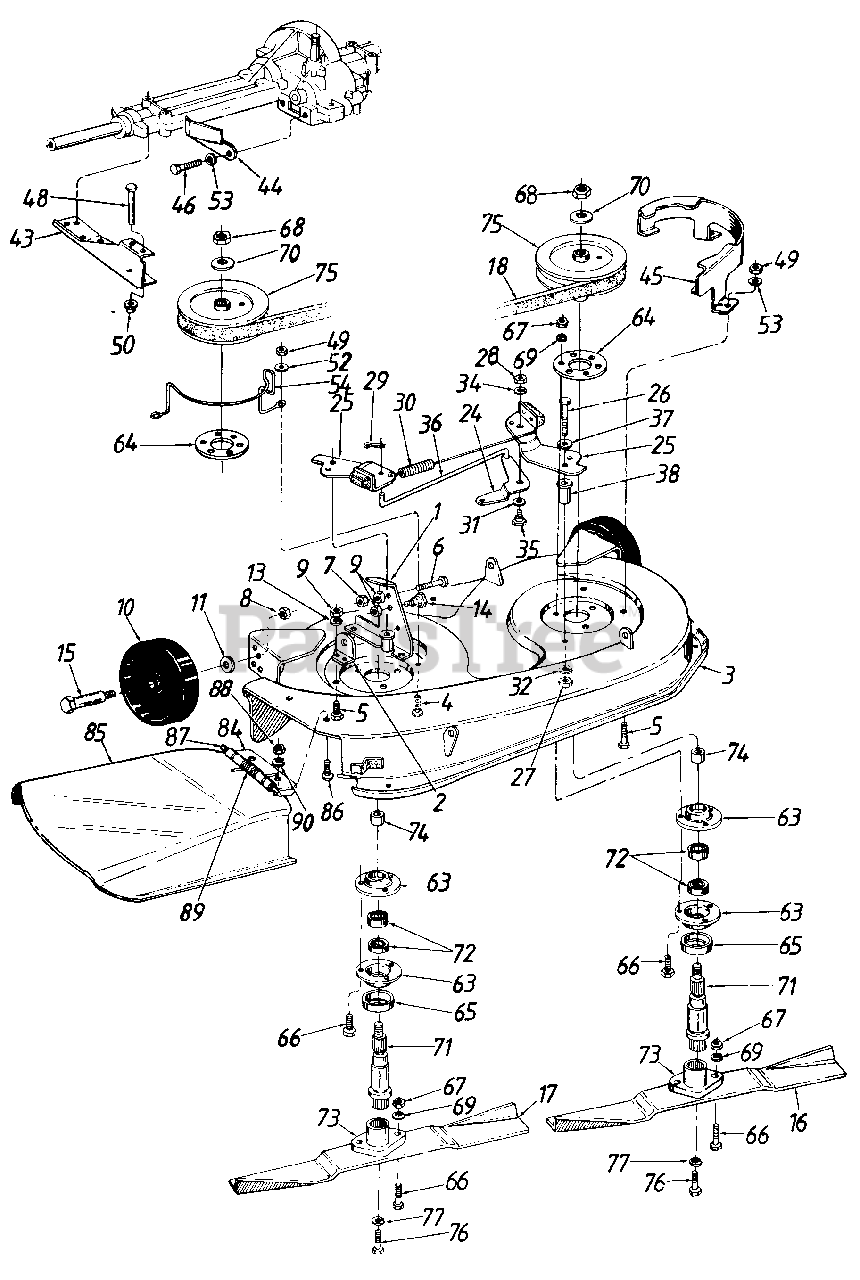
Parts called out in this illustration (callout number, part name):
1	Deck Disengagement Brkt.
2	Rear Deck Brkt. R.H.
3	32" Deck Ass'y.
4	Hex Bolt 1/4-28 x 1.75" Lg.
5	Hex Bolt 1/4-20 x .62" Lg.
6	Hex Wash. Hd. Scr. 1/4-20 x 1.5" Lg.
7	Hex L-Nut 1/4-20 Thd.
8	Hex L-Nut 3/8-16 Thd.
9	Hex Nut 1/4-20 Thd.
10	Deck Wheel
11	Bell-Wash. .380" I.D. x .88
13	L-Wash. 1/4" I.D.
14	Shld. Bolt .500" Dia. x .215"
15	Shld. Bolt .498" Dia. x 1.53"
16	L.H. High-Lift Blade
17	R.H. High-Lift Blade
18	V-Belt
24	Spacer 3/4" I.D. x 1-1/4" O.D. x 3/16"
25	Deck Brake Brkt. Ass'y.
26	Hex Bolt 5/16-18 x 3.25" Lg.
27	Hex Nut 5/16-24 Thd.
28	Hex L-Nut 1/4-28 Thd.
29	Hex Nut 1/4-28 Thd.
30	Extension Spring 4.35" Lg.
31	Spacer 1/4" I.D. x 3/8" O.D. x 1-5/16"
34	Hex Bolt 3/8-16 x 1" Lg.
35	Hex Bolt 1/4-20 x 2.5" Lg.
36	Wave Washer
37	Shld. Spacer .27" Lg.
38	Spacer 1.46" Lg.
43	Lower Outside Belt Guard
44	Lower Inside Belt Guard
45	Belt Guard Deck R.H.
46	Hex Bolt 1/4-20 x .62" Lg.
49	Hex Nut 1/4-20 Thd.
50	Speed Nut 1/4" Rod
52	5" Dia. Pulley
53	L-Wash. 1/4" I.D.
54	Bell-Wash. 5/16" I.D.
63	Bearing Housing
64	Reinforcement Plate
65	Bearing Shield
66	Hex Bolt 5/16-24 x 1.0" Lg.
67	Hex Nut 5/16-24 Thd.
68	Hex Jam Nut 5/8-18 Thd.
69	L-Wash. 5/16" I.D.
70	Bell-Wash. 5/8" I.D.
71	Blade Spindle
72	Ball Bearing
73	Blade Adapter
74	Spacer
75	5" Dia. Pulley
76	Hex Bolt 3/8-24 x 1.0" Lg.
77	L-Wash. 3/8" I.D. H.D.
84	Chute Bracket
85	Chute
86	Truss.-Mach. Scr. 1/4-20 x .75" Lg.
87	Hinge Pin
88	Hex Nut 1/4-20 Thd.
89	Torsion Spring 1.14" Lg.
